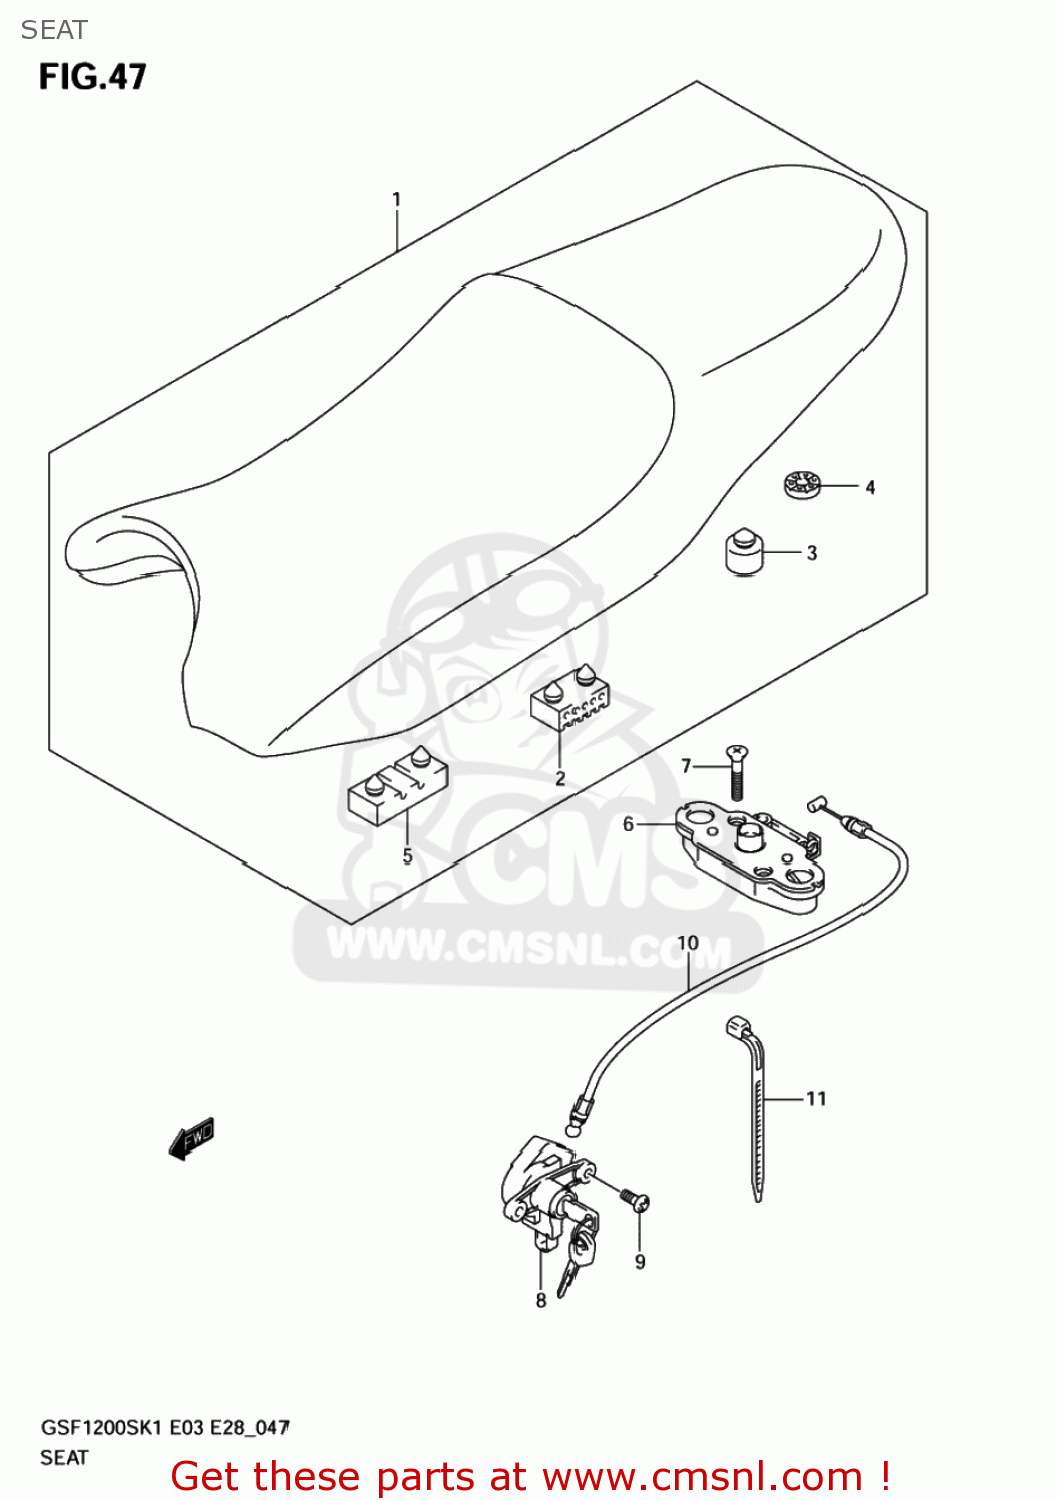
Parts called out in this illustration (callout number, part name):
1	SEAT ASSY
2	CUSHION,SEAT(40X20X15)
3	CUSHION
4	CUSHION
5	CUSHION
6	BRACKET,SEAT SUPPORT,RIGHT
7	SCREW
8	LOCK SET,SEAT & HELMET
9	SCREW(6X14)
10	CABLE,TANK LOCK
11	CLAMP(L:125)
